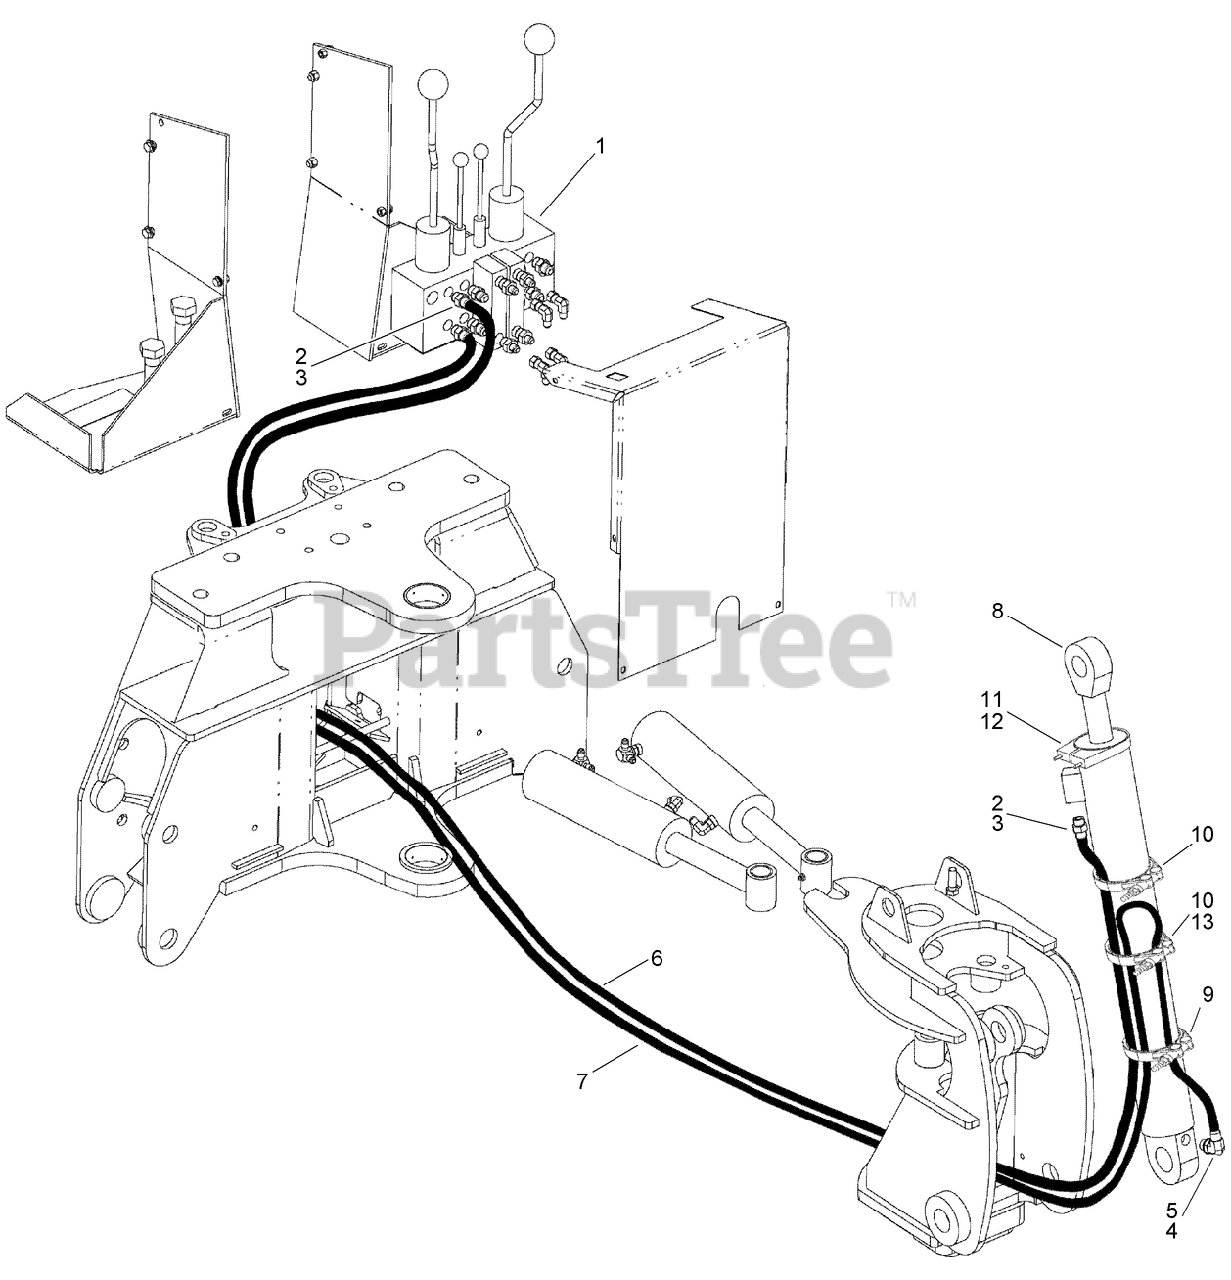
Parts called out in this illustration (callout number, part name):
1	HYD CONTROL VALVE ASM
2	CONNECTOR-Str Thd 1/2, 37FL-ORB 1/2
3	O-RING
4	ELBOW-90 DEG
5	O-RING
6	HOSE-to rod end of boom cylinder
7	TUBE-to closed end of boom cylinder
8	HYD CYLINDER ASM
9	CLAMP-Hose Type F #60
10	CLAMP-HOSE
12	CLAMP-Insul 19.0 mm 3/8 in Bolt ZND
13	SADDLE-SUPPORT, TUBE
